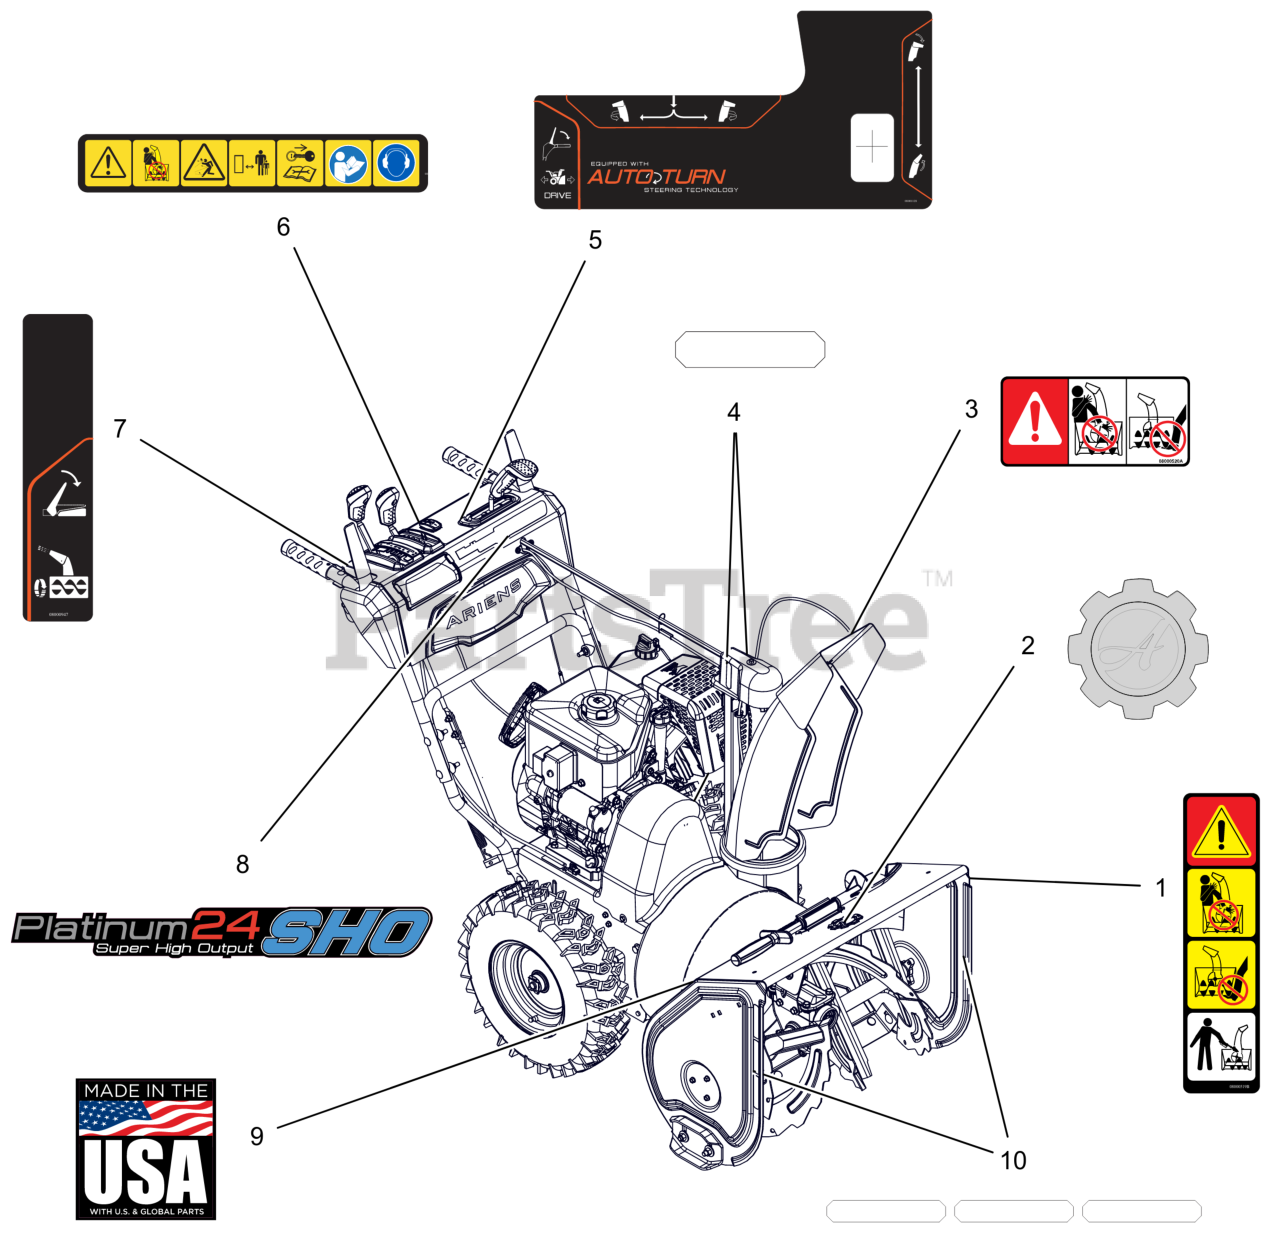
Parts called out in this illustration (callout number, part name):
1	DECAL, DANGER - ROTATING PARTS
2	DECAL, ARIENS-GEAR BADGE -THK
3	DECAL, DANGER
4	DECAL,REFLECTIVE,GEAR COVER
5	DECAL,CONTROL-LG QT2
6	DECAL,DASH - SAFETY
7	DECAL,CONTROL-RH CONTROL
8	DECAL, DASH, PLATINUM 24 SHO
9	DECAL, MADE IN USA
10	DECAL,REFLECTIVE,HOUSING
